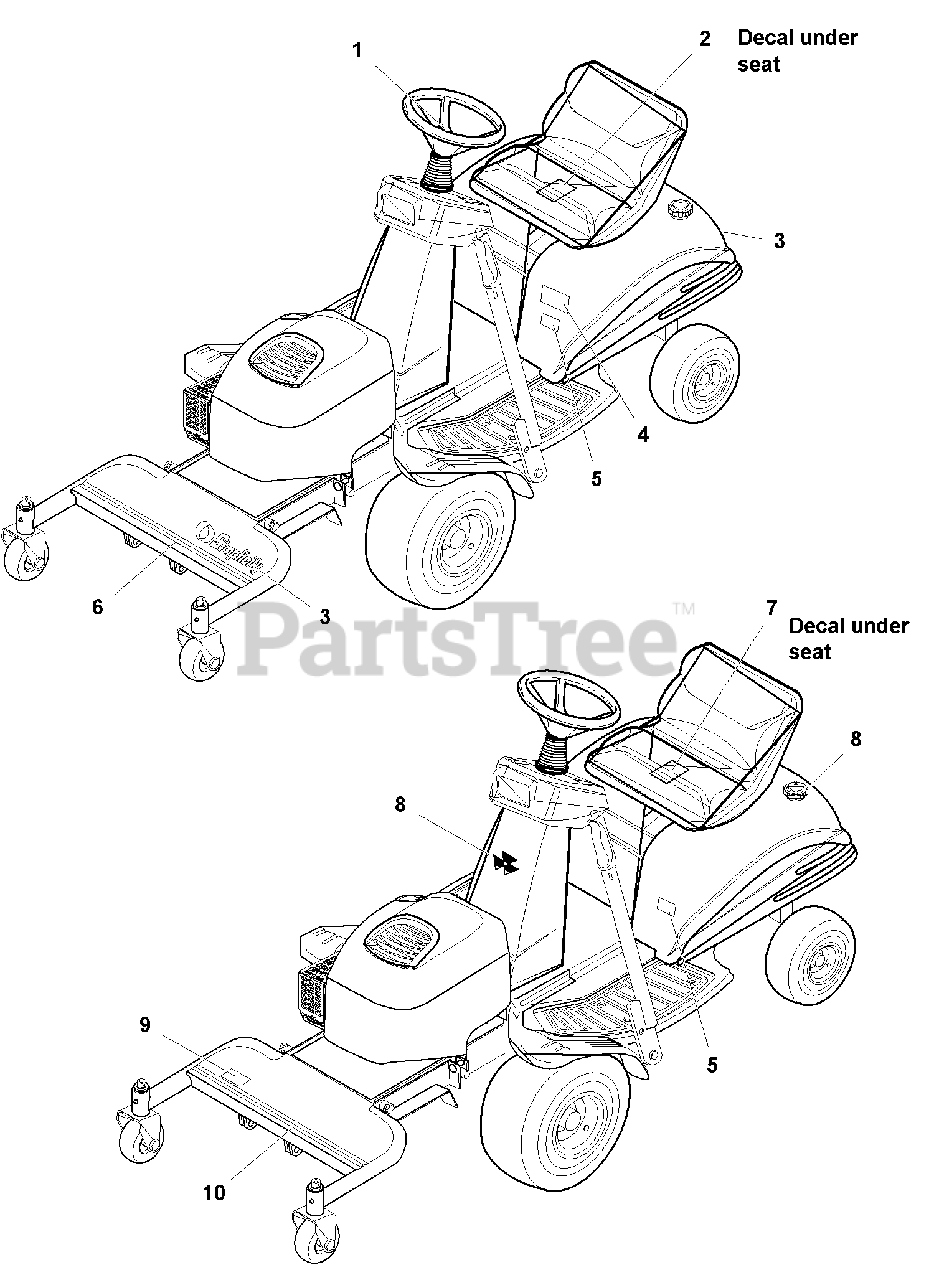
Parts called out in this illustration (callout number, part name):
1	DECAL, Icon, Simplicity
2	DECAL, Touch-up Paint, Deep Orange and Black
3	DECAL, Simplicity, Silver & Blue, w/Icon
4	DECAL, Lancer, Silver & Blue
5	DECAL, 15HP
5	DECAL, 17HP
6	DECAL, Stripe, Blue & Silver
7	DECAL, Touch-up Paint, Red and Black
8	DECAL, Massey Ferguson, 3 Triangle Logo
9	DECAL, Model 4416
9	DECAL, Model 4417
10	DECAL, Stripe, Massey Ferguson
